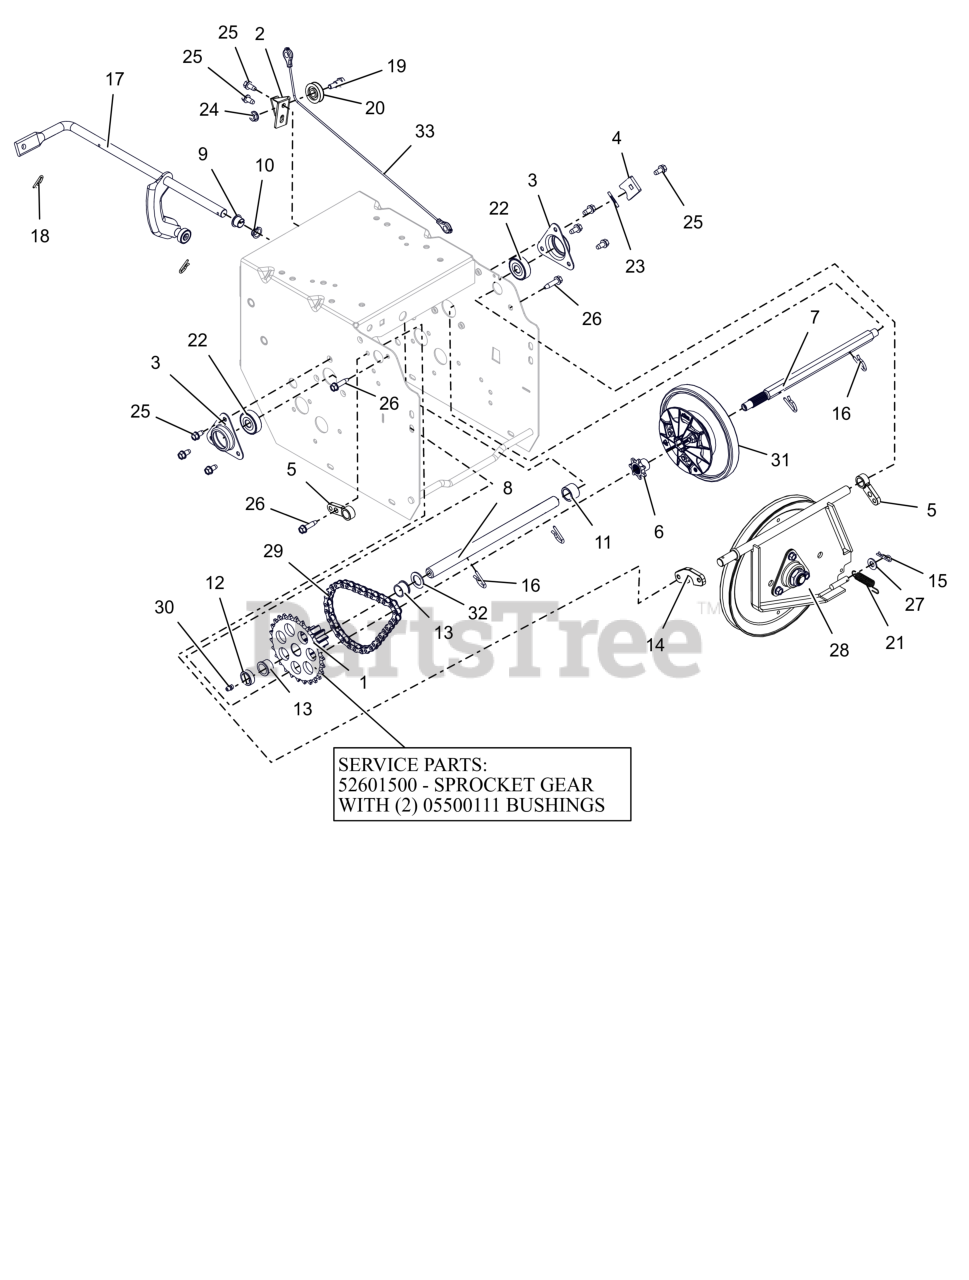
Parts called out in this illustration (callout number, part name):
1	PINION & SPROCKET
1	PINION & SPROCKET W/BUSHINGS
2	BRACKET, CABLE PULLEY
3	FLANGE, BEARING
4	TAB, ANTI ROTATION
5	SUPPORT BUSHING, SWING GATE
6	SPROCKET, PINION 7T W/SPLINE
7	SHAFT, HEX W/SPLINE TRACK
8	SHAFT, PINION TRACK
9	BUSHING, POLYLINER-.50 SPLIT
10	BUSHING, POLYLINER-.50 SNAPIN
11	SPACER, .635X.880X.611
12	BSHG-SLV, .635X.880X.305
13	BSHG-FLG .625X.750X.500X.875
14	SPACER, SWING GATE
15	PIN, HAIR #213 .08X1.19 ZCC
16	PIN, SPRING CLIP
17	ARM, SHIFT-SMALL DASH (ASSY)
18	CLIP, SPRING
19	BOLT, SHLDR -.375 X .375 X .25-20
20	PULLEY, CABLE
21	SPRING, EXT. .043X.438X1.64
22	BRG-BALL .437X1.375X.437
23	@PIN-GRV .125X1.00 TP E ALLOY
24	NUT-LK-CTR-FLG .25-20 ZC120
25	SCR-TAP .25-20X.50 HWH ZCC
26	SCR,TAP .25-20X.75 HWH TR ZCC
27	WSHR,FLT .344X.688X.065 ZCC
28	PLATE, SWING - ASSEMBLY
29	CHAIN - #41, 32 PITCHES
30	ZERK,FITTING .25X.125 DRIVE IN
31	DISC, FRICTION DRIVE-ASSEMBLY
32	WSHR, FLT .630X1.005X.062 ZCC
33	CABLE, LOWER TRACTION (CMPCT)
